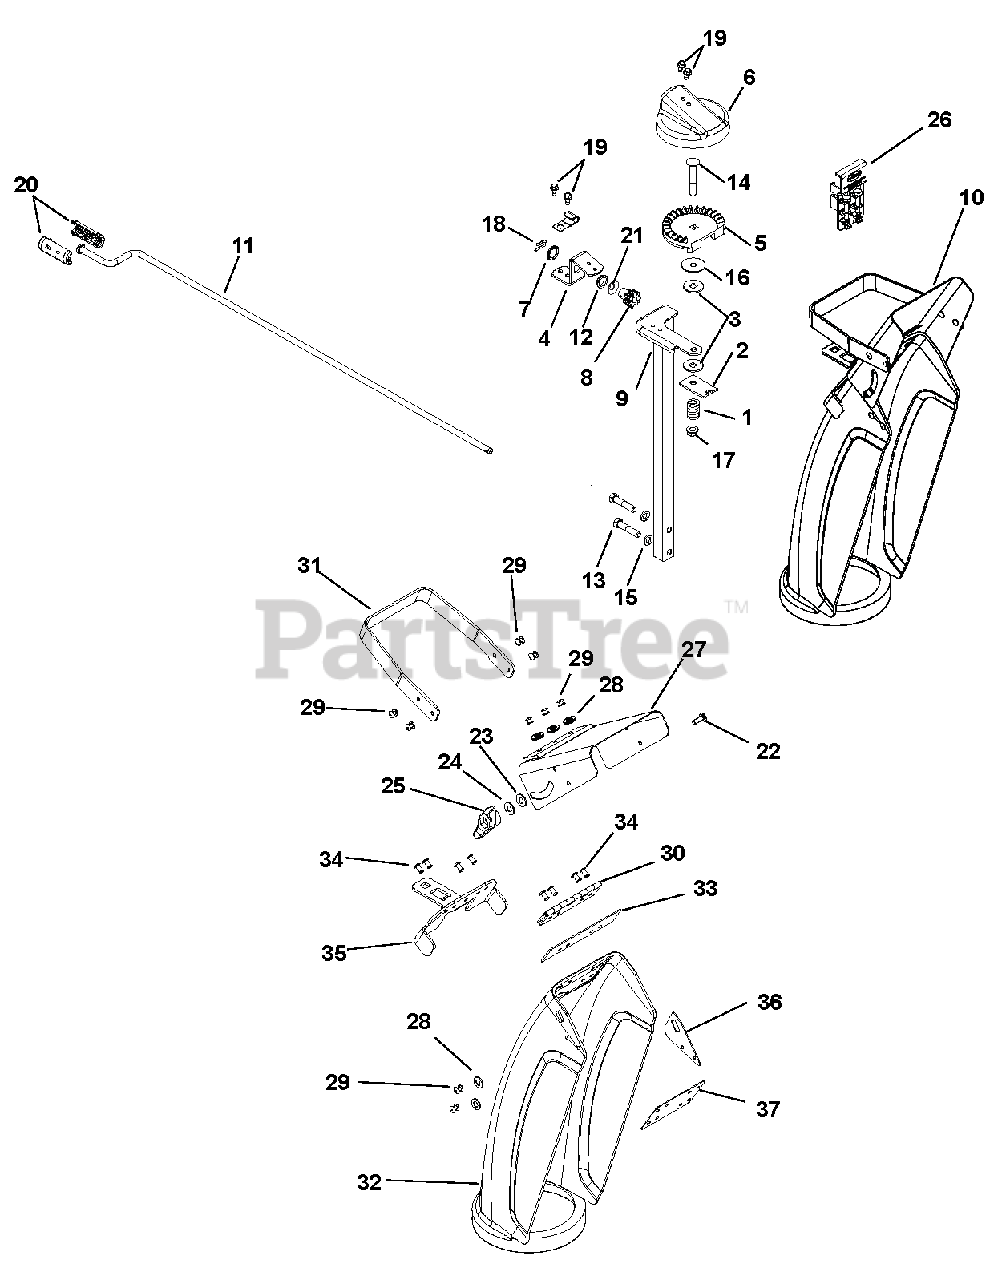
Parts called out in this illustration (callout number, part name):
1	SG-COMP .187X.56X1.62
2	PLATE, FRICTION
3	FRICTION WASHER
4	BRACKET, PINION GEAR
5	CHUTE GEAR
6	GEAR COVER
7	PUSHNUT .625
8	PINION GEAR W/BRACKET
9	CHUTE PEDESTAL, TALL COMPACT
10	CHUTE, DISCHARGE W/CAP & DECAL
11	ROD, CHUTE CRANK, COMP&SNOTEK
12	BUSHING, POLYLINER-.63 SNAPIN
13	@BLT-HEX .38-16X1.75 GR5 YWZC
14	@BLT-RDHDSQNK .38-16X2.50 G5YZ
15	@WSHR-LK .38X.094 REG YWZC
16	@WSHR-FL-STL .406X1.25X.10 ZC
17	@NUT-LK-TOP-FLG .38-16 YWZC
18	PIN, SPRING CLIP
19	SCR-TAP .25-20X.50 HWH TR YWZ
20	KNOB, CHUTE CRANK - SNAP BLK
21	WSHR-THRST .625 X 1.0 X .03
22	@BLT-RHDSSQNK .31-18X1.00 G5YZ
23	WSHR-FL-NY .375X.75X.060
24	@WSHR-FL-STL.344X.688X.065YWZC
25	KNOB,WING .31-18 UNC NYL/TALC
26	HOLDER W SMALL SHEAR BOLT /NUT
27	CAP, SMALL DEFLECTOR-MANUAL
28	WSHR-FL-STL .196X.500X.06 YZ
29	RVT-POP .187 YZ
31	DEFLECTOR HANDLE
32	CHUTE, PLASTIC DISCHARGE
33	CAP SEAL 5.25
34	RIVET, #66 STEEL POP PD BLACK
35	CHUTE MOUNT BRACKET
36	BACKING PLATE, CHUTE CAP
37	PLATE, BACKING - PLASTIC CHUTE
